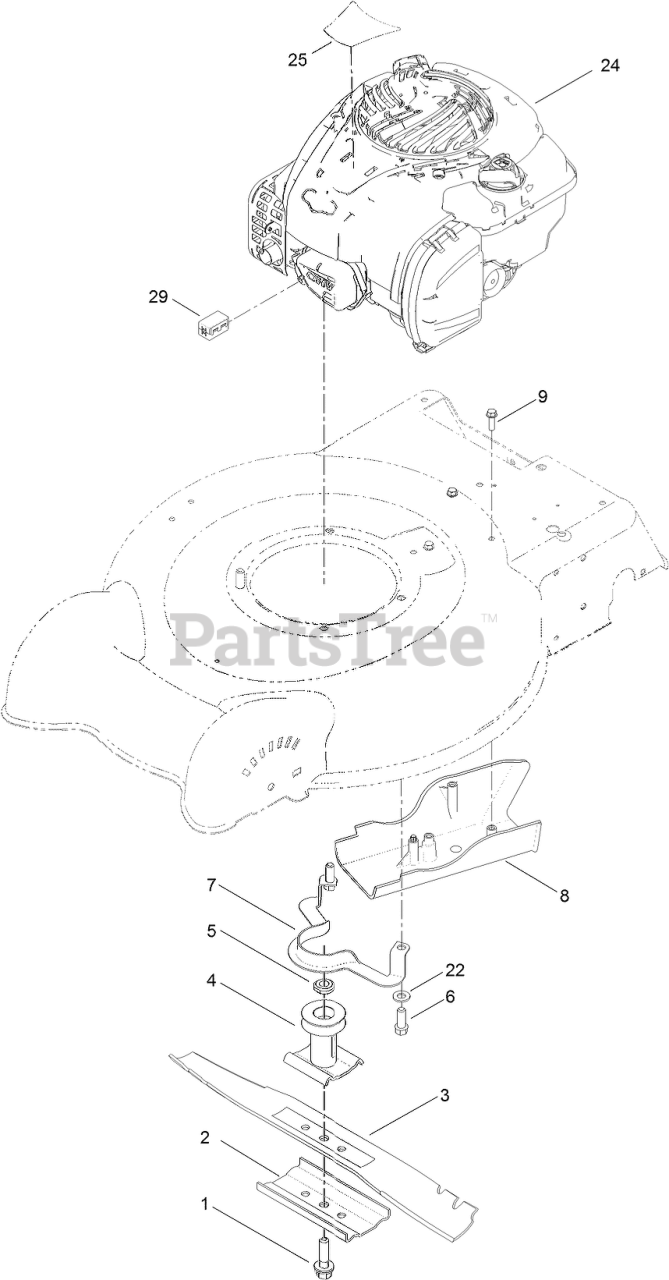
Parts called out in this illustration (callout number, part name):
1	BOLT-BLADE
2	SUPPORT-BLADE
3	BLADE-20 INCH
4	DRIVER-BLADE
5	SPACER-DRIVER
6	SCREW-TAPTITE
7	Guide-Belt
8	COVER-BELT
9	SCREW-HWH
22	WASHER-FLAT
25	DECAL-ENGINE
29	FERRITE-CLAMP
